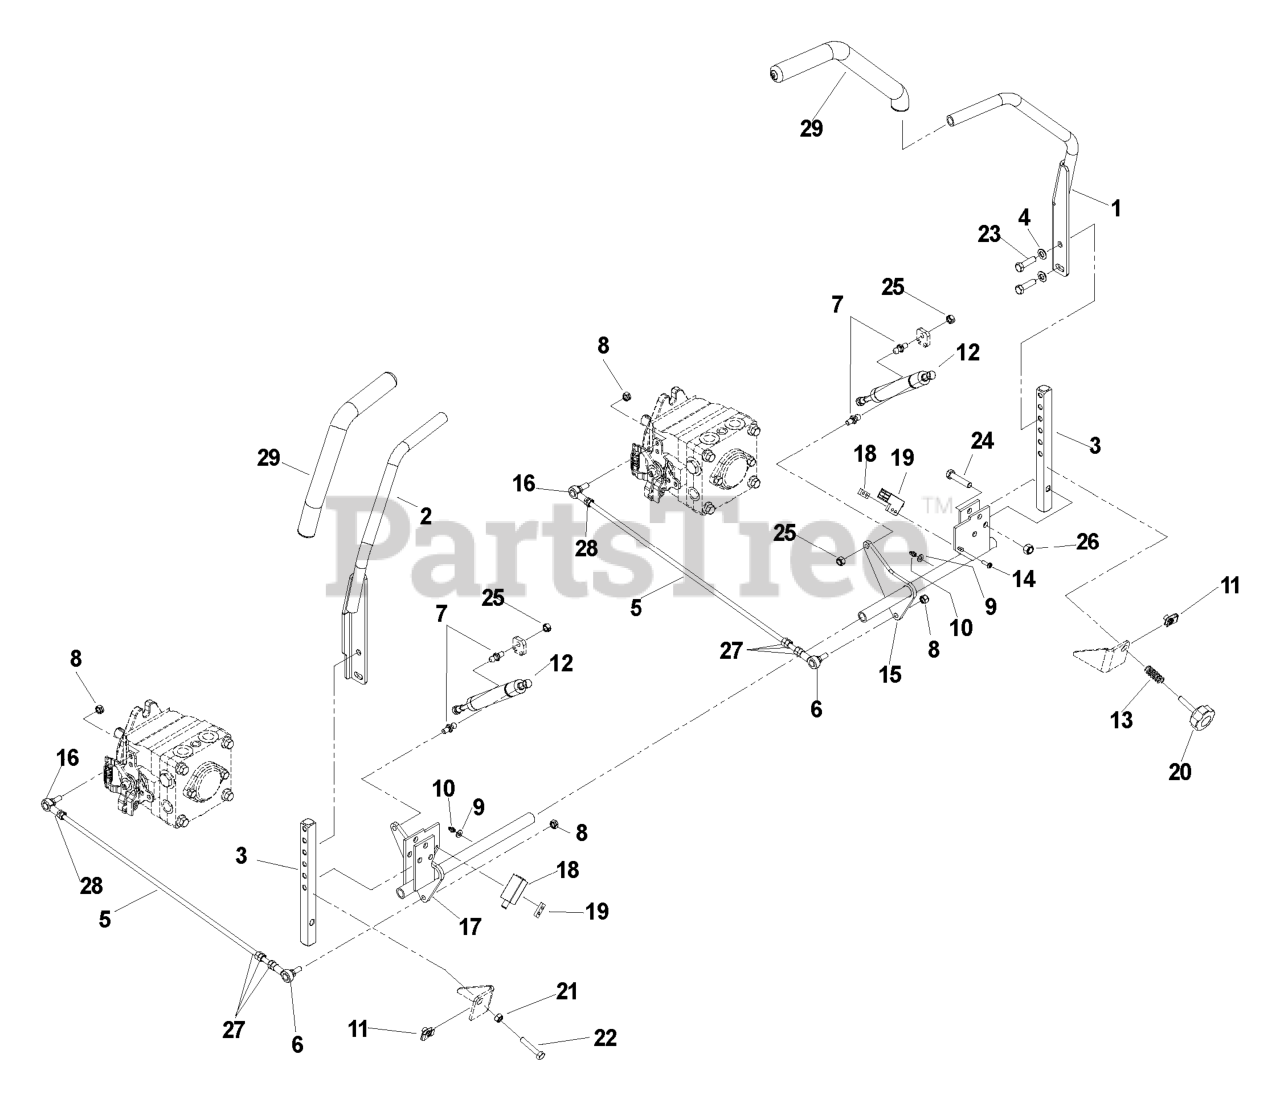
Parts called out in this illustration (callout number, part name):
1	LT DRIVE LEVER WLDMT
2	RT DRIVE LEVER WLDMT
3	CONTROL ARM
4	WASHER, 3/8 DISC SPRING SPEC
6	SPHERICAL ROD END, RH
7	STUD.BALL.10MM
8	NUT 5/16F NYLOC
10	ZERK
11	U-CLIP 5/16-18 NUT RETAINER
12	DAMPENER
13	COMPRESSION SPRING
14	SCREW #10-24 X 5/8
15	CONTROL WLDMT, LT
16	SPHERICAL ROD END, LH
17	CONTROL WLDMT, RT
18	TAPPED PLATE
20	ADJUSTMENT KNOB
21	NUT 5/16C HEX
22	HCS 5/16-18X1-3/4 TPBLT
23	HCS 3/8-16X1.GRD.5.ZD
24	HCS 3/8-16 X 1 3/4 GR5
25	NUT 5/16C CENTERLOCK
26	NUT 3/8-16 NYLOC
28	NUT 5/16F LEFTHAND
